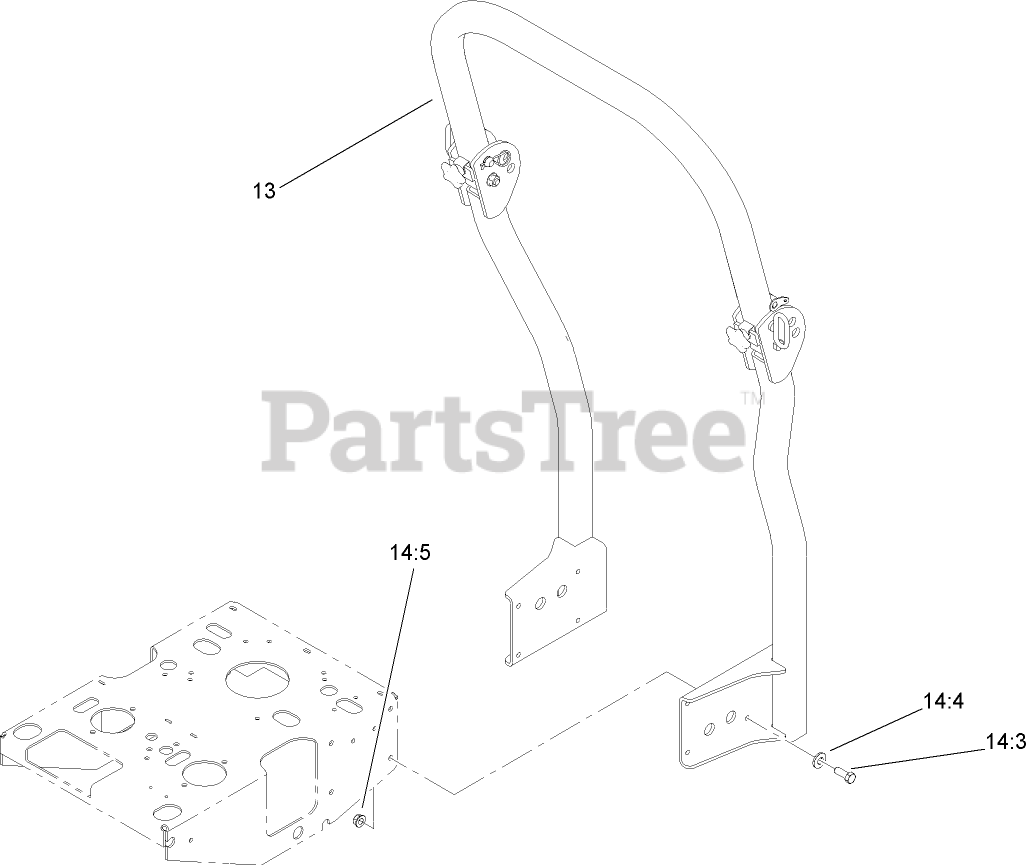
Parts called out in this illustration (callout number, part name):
13	ROPS ASM
14:3	SCREW-HH
14:4	WASHER-BELLEVILLE
14:5	NUT-HHF, WHIZ
